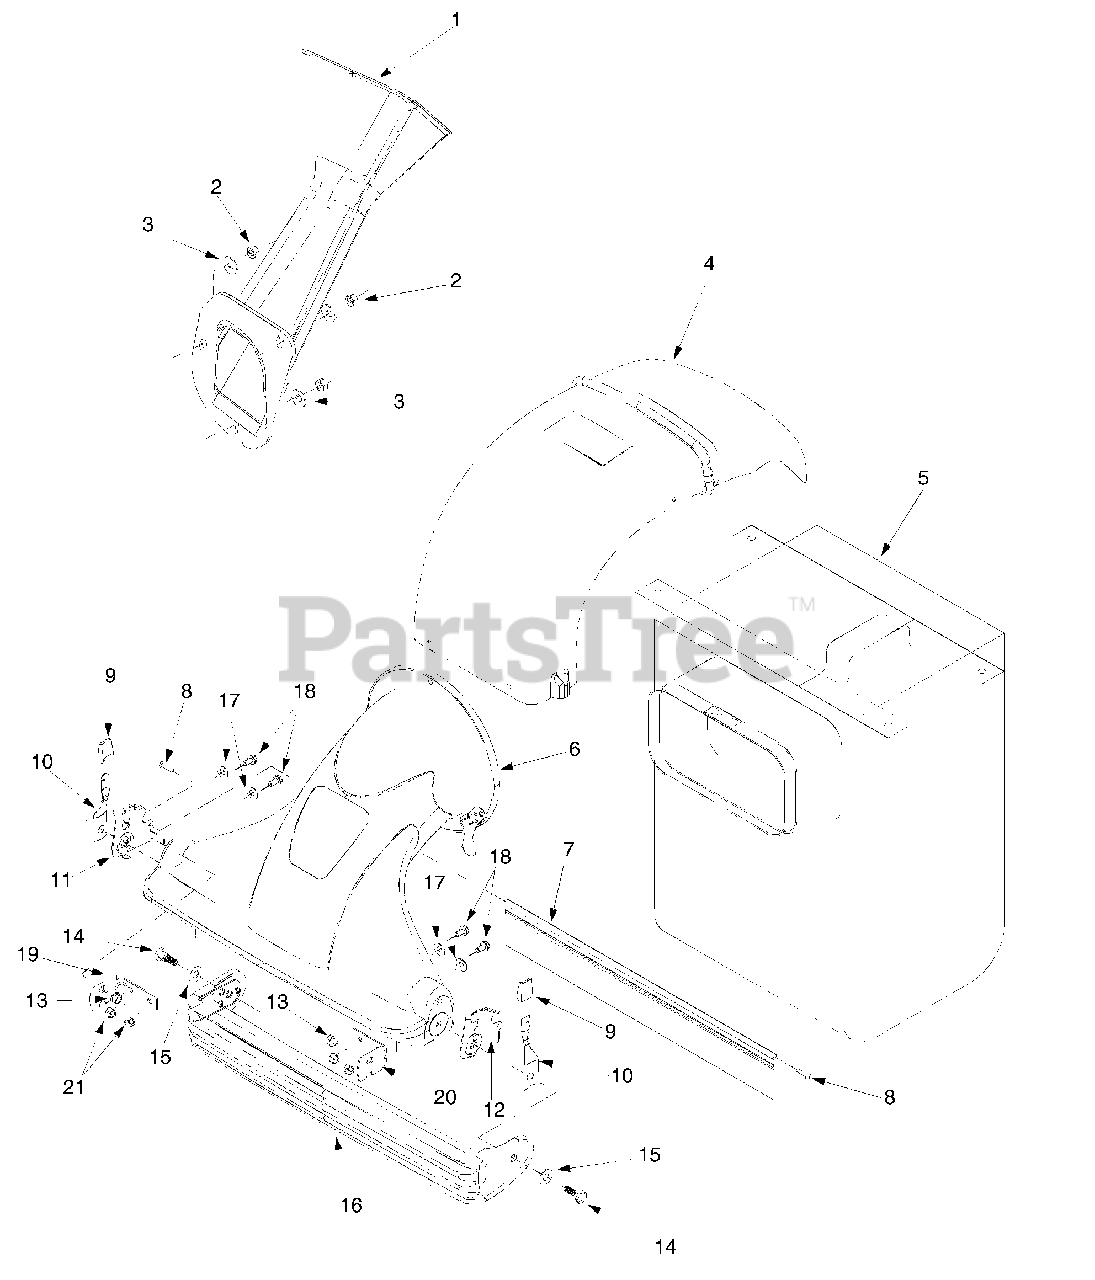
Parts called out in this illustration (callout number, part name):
2	Hex Nut 5/16-18
3	Bell Washer .340 ID x .872 OD
4	Discharge Chute
5	Bag
6	Nozzle Asm
7	Nozzle Flap
9	Height Adjustment Knob
10	Spring Lever
13	Hex Flange Lock Nut 3/8-16
14	Shoulder Screw
15	Flat Washer .510 x 1.12 x .060
17	Flat Washer .28 ID x .74 OD
18	Hex Cap Screw 1/4-20 x .625
19	Nozzle Reinforcement Bracket RH
20	Nozzle Reinforcement Bracket LH
21	Hex Flange Lock Nut 1/4-20
